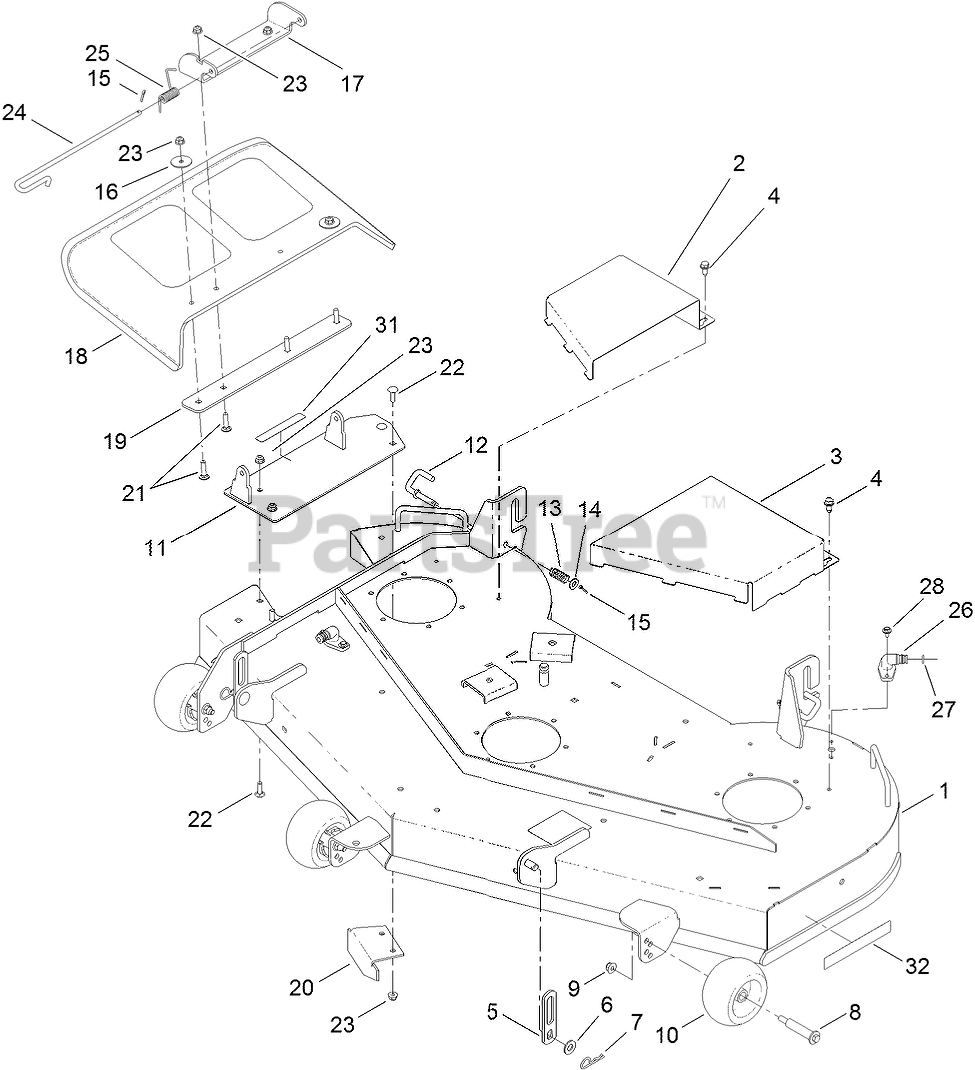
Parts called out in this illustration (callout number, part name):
1	54 INCH DECK ASM
2	COVER-BELT, RH
3	COVER-BELT, LH
4	SCREW-HWHTF
5	LINK-LIFT
6	WASHER-FLAT
7	PIN-COTTER
8	BOLT-SHOULDER
9	NUT-HF, NI
10	ROLLER-SCALP, ANTI
11	PLATE-COVER
12	PIN-LATCH
13	SPRING-COMPRESSION
14	WASHER-FLAT
15	PIN-COTTER
16	WASHER-FLAT
17	BRACKET-DEFLECTOR, UPPER
18	DEFLECTOR
19	PLATE-DEFLECTOR
20	BAFFLE-CUTOFF
21	SCREW-CARR
22	SCREW-CARR
23	NUT-HF, NI
24	PIN-CHUTE
25	SPRING-TORSION
26	FITTING-WASHOUT
27	O-RING
28	SCREW-HHFTF
31	DECAL-DANGER
32	DECAL-RECYCLER
